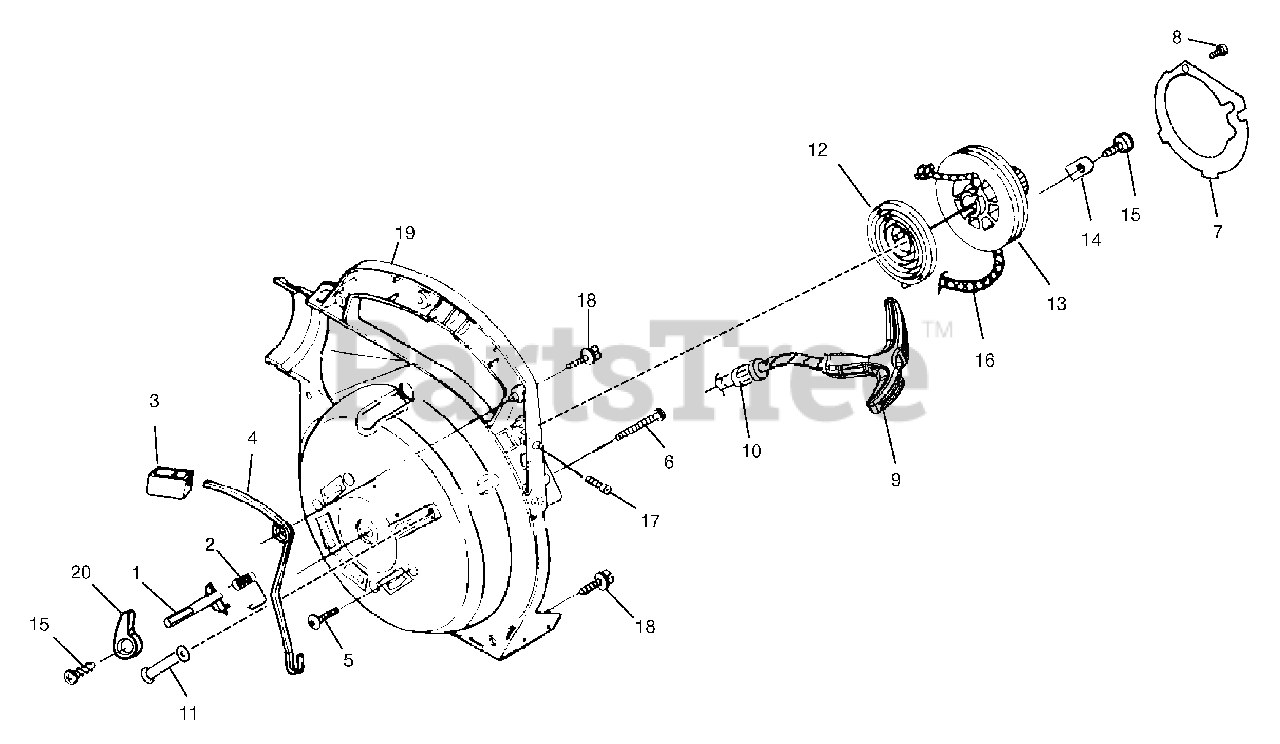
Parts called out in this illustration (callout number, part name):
1	THROTTLE LATCH
2	THROTTLE LATCH SPRING
3	THROTTLE TRIGGER
4	THROTTLE LEVER
5	SCREW (10-24 x 3/4 in TRUSS Hd)
6	SCREW (10 x 1-5/8 in Hex Hd)
7	ROTOR PLATE
8	SCREW (#6 x 1 3/8)
9	STARTER GRIP (YELLOW)
10	BUSHING STARTER
11	STARTER ROPE GUIDE
12	SPRING AND CONTAINER
13	STARTER PULLEY
14	RETAINING BRACKET
15	SCREW (10-24 x 1/2 in TORx TRUSS Hd)
16	STARTER ROPE
17	SCREW (8-32 x 5/8 in FIL Hd)
18	SCREW (10-14 x 3/4 in TORx TRUSS Hd)
19	INNER VOLUTE HOUSING
20	THROTTLE CONTROL KNOB
